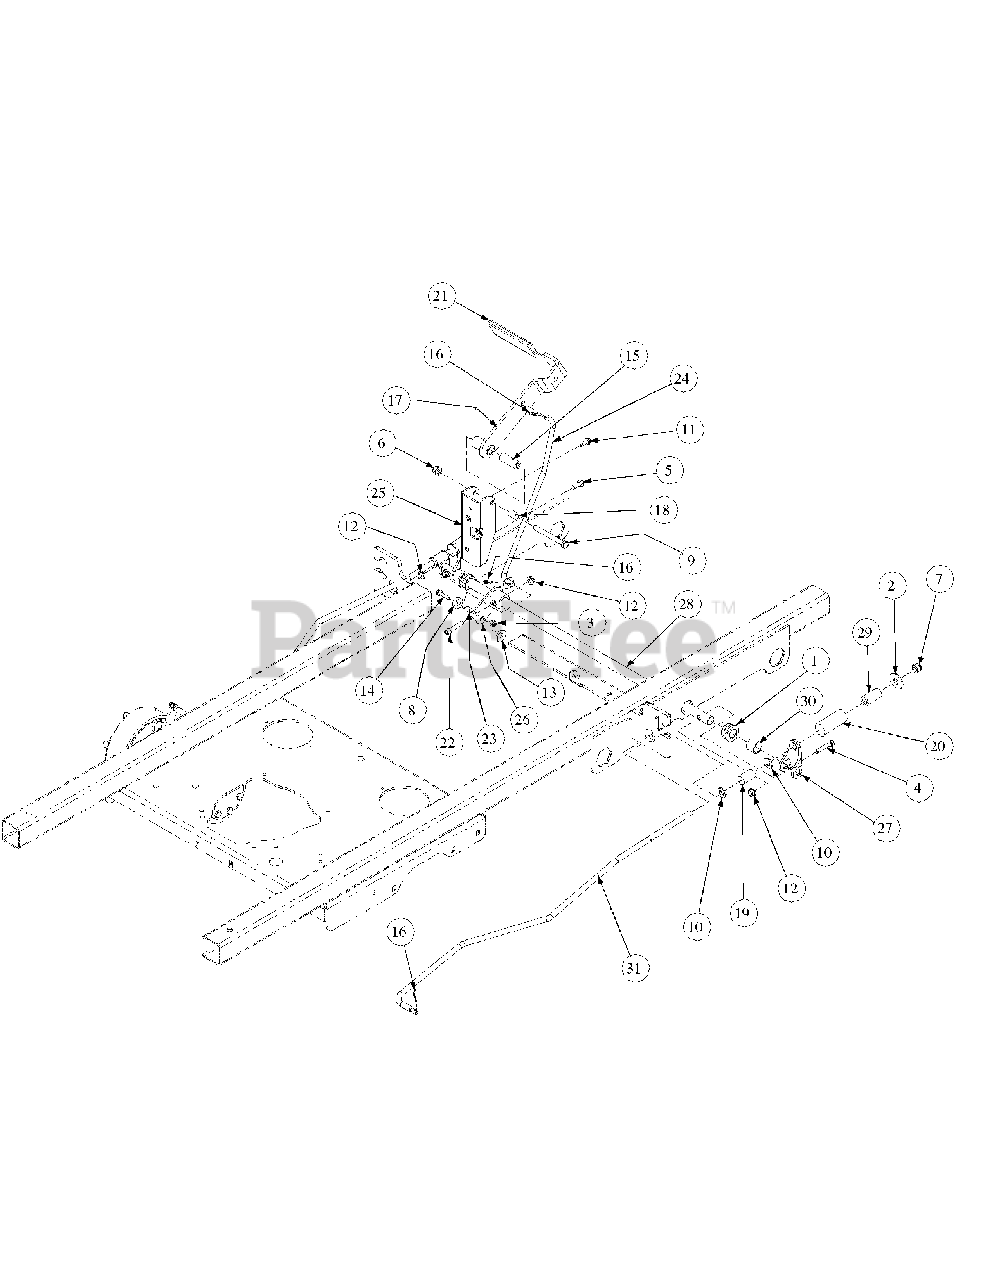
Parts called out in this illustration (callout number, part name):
1	Hex Flange Bearing, .752 ID
2	Washer, 1/2
3	Lock Nut, Nylon Insert, 1/4-20
4	Hex Cap Screw, 5/16-18 x 1-1/2
5	Hex Cap Screw, 5/16-18 x 1.0
6	Flange Lock Hex Nut, 3/8-16
7	Nut, 7/16-14, Nylock
8	Spacer, Control Rod
9	Hex Cap Screw, 3/8-16 x 3-1/4
10	Flat Washer, .469 ID, .875 OD, .105
11	Screw, TT, 1/4-20, 0.75, Hex Index Washer
12	Nut, Lock, Hex Flange, 5/16-18
13	Flat Washer, .406 ID x 1.0 OD x .105
14	Screw, TT, 1/4-20, 1.0, Hex Index Washer
15	Spacer, .39 x .63 x 1.75
16	Cotter Pin, .072 x 1.12 Lg
17	Brake Handle
18	Spacer, .375 x .50 x .75 Lg
19	Neutral Brake Spring
20	Force Brake Spring
21	Parking Brake Grip
22	Socket Head Capscrew, 5/16-18 x 1.50
23	Spacer, Pump Release
24	Brake Rod
25	Parking Brake Mounting Bracket
26	Brake Arm Assembly
27	Brake Arm Bracket
28	Pivot Brake Shaft
29	Hose, .5 ID x .78 OD, Low Pressure
30	Spacer, .76 ID x 1.0 OD x 3/4
31	Connector Rod Rod
